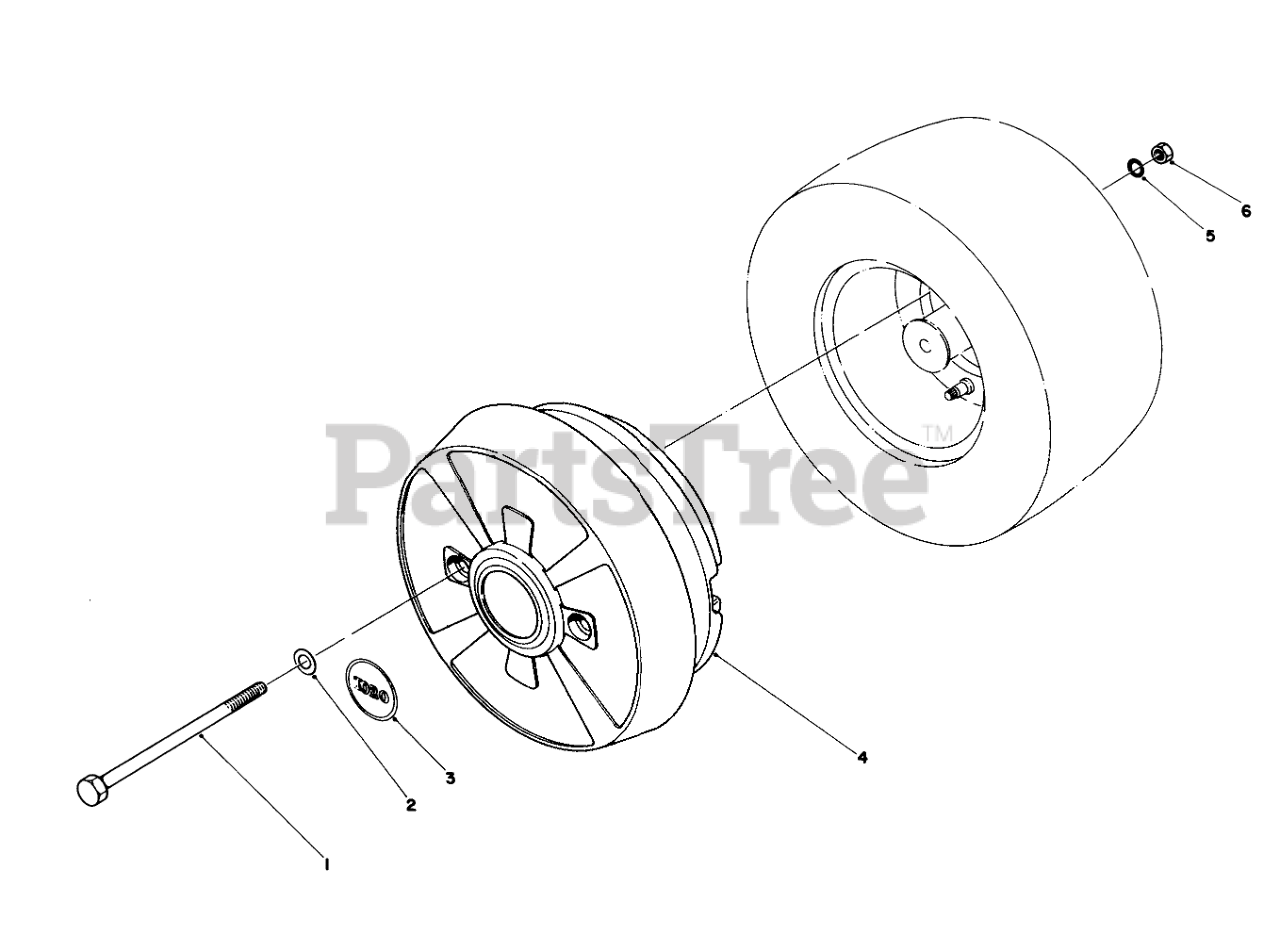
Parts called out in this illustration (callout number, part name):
1	SCREW-HH
2	WASHER-FLAT
3	Decal
4	WHEEL WEIGHT
5	WASHER-LOCK
6	NUT-HEX
